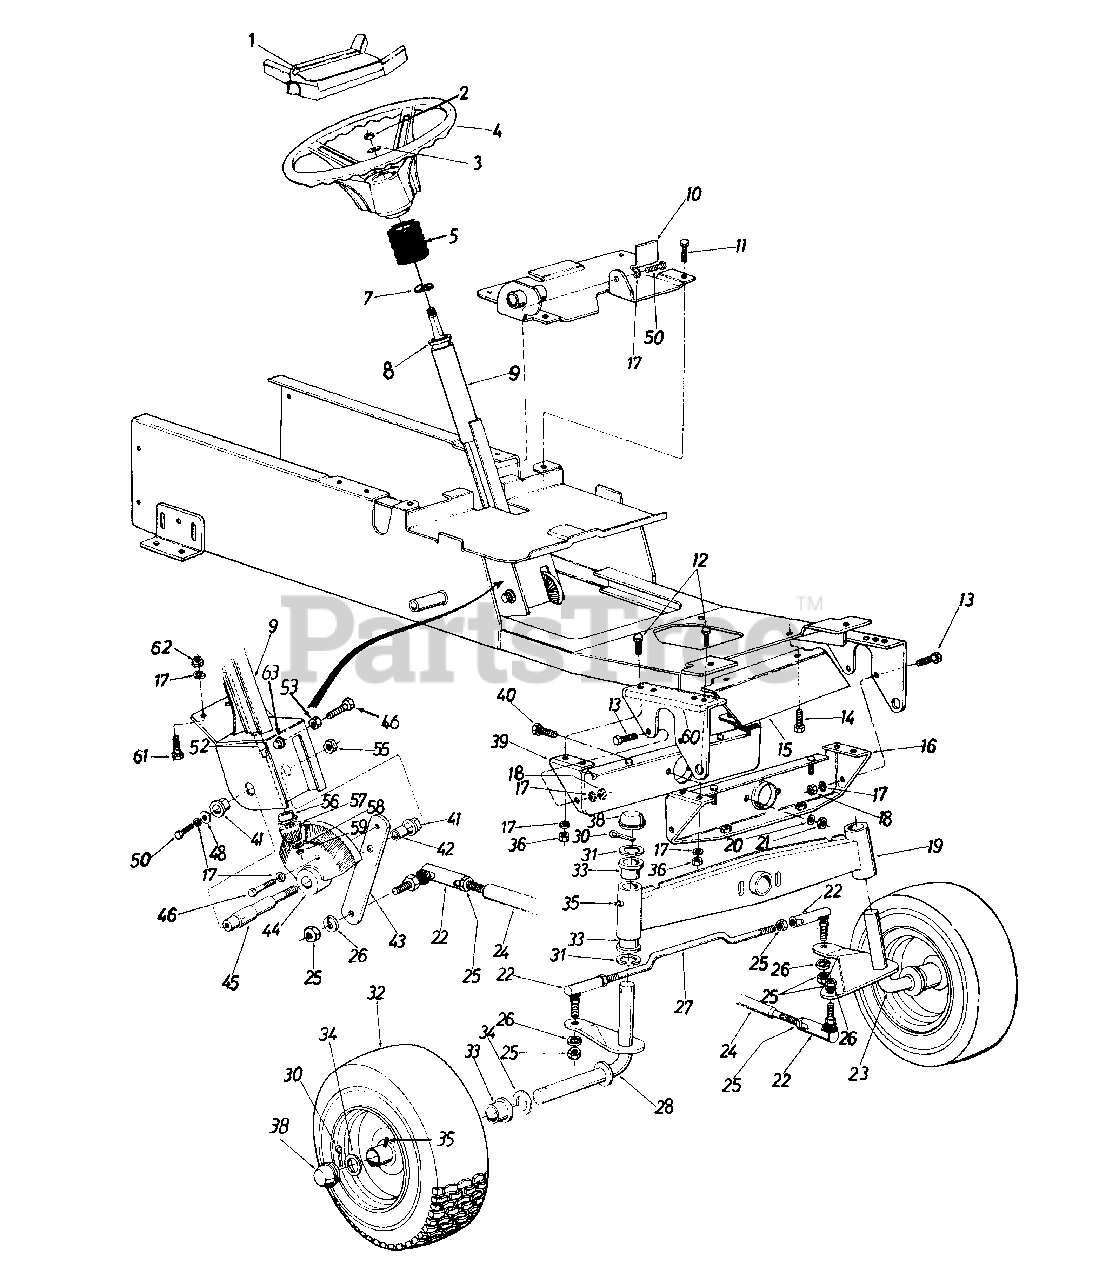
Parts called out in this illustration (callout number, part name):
1	Steering Wheel Insert
2	Hex Cent. L-Nut 5/16-24 Thd.
3	Bell-Wash. 5/16" I.D.
4	Steering Wheel
5	Steering Bellow
8	Ball Brg. .63" I.D. x 1.38" O.D.
12	Hex Bolt 3/8-16 x 1.5" Lg.
13	Hex Bolt 3/8-16 x 1" Lg.
14	Hex Wash. S.F. Tap Scr.3/8-16 x 1.25" Lg.
18	Hex Nut 3/8-16 Thd.
19	Pivot Bar Assembly
20	Bell-Wash. 3/8" I.D.
21	Hex Cent. L-Nut 3/8-16 Thd.
22	Drag Link End
23	Axle Assembly-L.H.
24	Drag Link
25	Hex Nut 1/2-20 Thd.
26	L-Wash. 1/2" I.D.
27	Tie Rod
28	Axle Assembly-R.H.
30	Cotter Pin 3/16" Dia. x 1.5" Lg.
31	Fl-Wash. 1.00" I.D. x 1.62"
33	Flange Brg. 1" I.D.
34	Fl-Wash. 1" I.D. x 1.25" O.D.
35	Grease Fitting
36	Hex Nut 3/8-16 Thd.
38	Dust Cover
41	Flange Brg. w/Flats .753" I.D.
42	Steering Gear Shaft Spacer
43	Steering Arm
44	Bevel Gear
45	Steering Gear Shaft
46	Hex Bolt 3/8-16 x 1.5" Lg.
48	Fl-Wash. .406" I.D. x 1.25" O.D.
50	Hex Bolt 3/8-16 x .75" Lg.
52	Steering Shaft
53	Hex Jam Nut 3/8-16 Thd.
55	Hex Ins. L-Nut 1/2-20 Thd.
56	Hex Flange Brg. .630 I.D.
57	Pinion Gear
58	Fl-Wash. 3/8" Dia.
59	Hex Cent. L-Nut 5/16-24 Thd.
62	Hex Nut 3/8-24 Thd.
